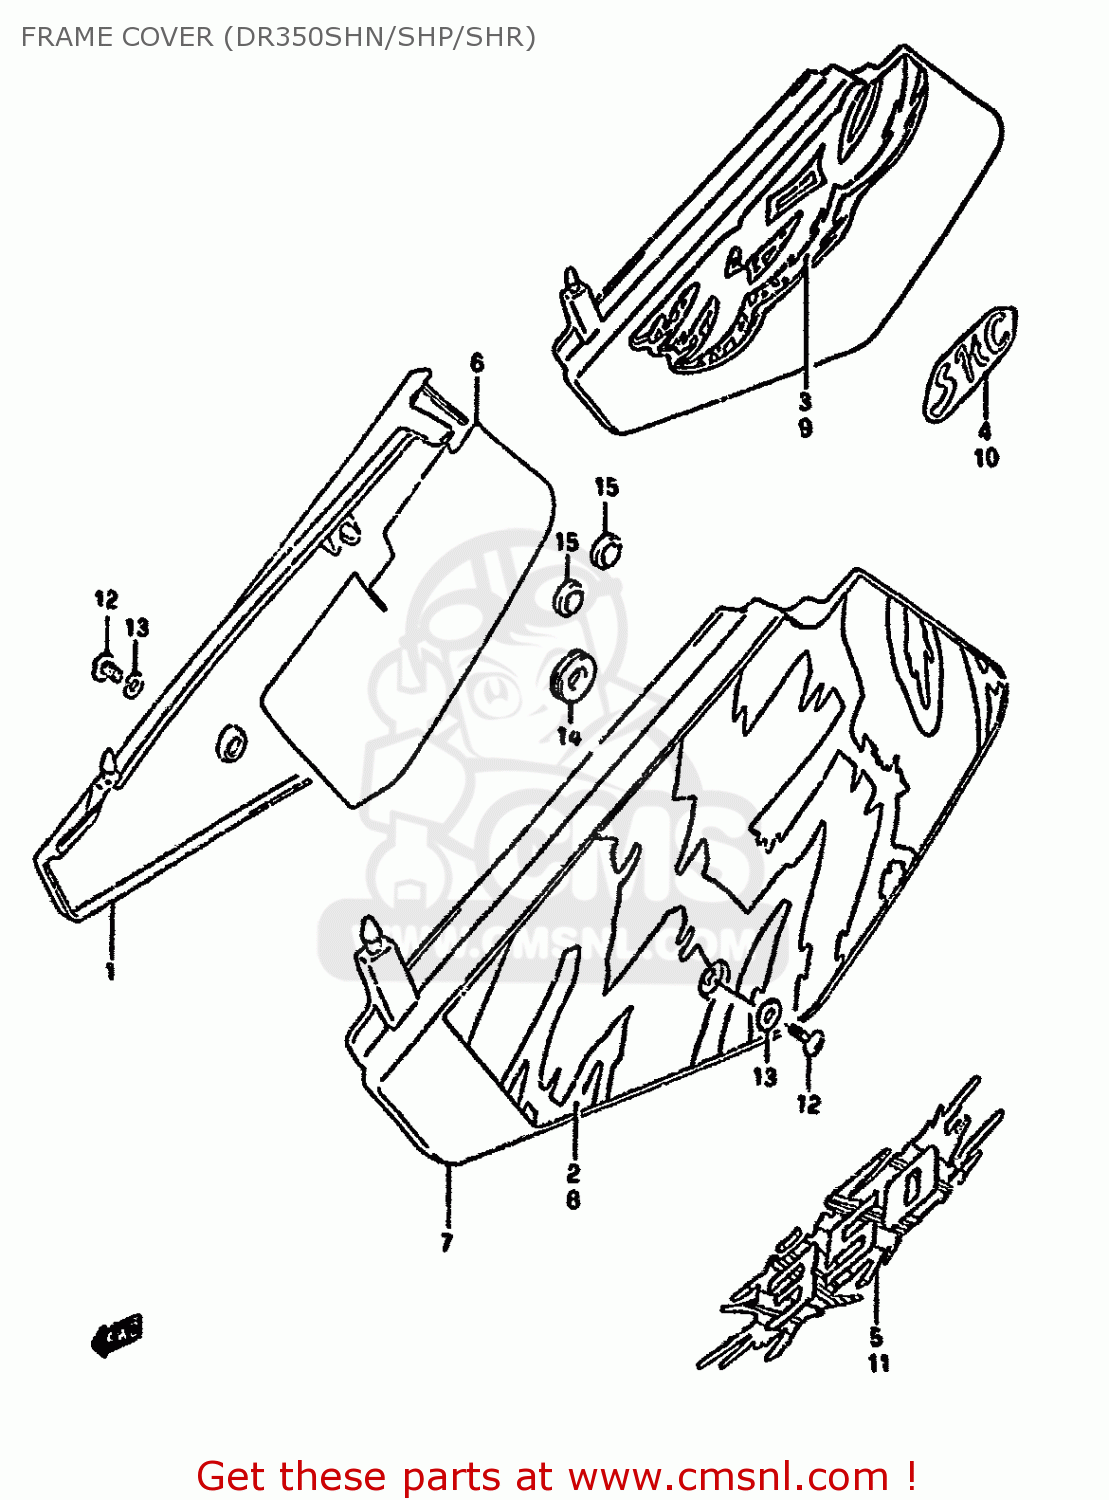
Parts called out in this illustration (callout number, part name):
1	COVER,FRAME,R(WHITE)
2	TAPE,FRAME COVER RH
3	EMBLEM,FRAME COVER,R
4	EMBLEM "SHC"
5	EMBLEM
6	SHIELD,FRAME COVER,R
7	COVER,FRAME,L(WHITE)
8	TAPE,FRAME COVER LH
9	EMBLEM,LH
10	EMBLEM "SHC"
11	EMBLEM
12	SCREW
13	WASHER
14	CUSHION
15	CUSHION
